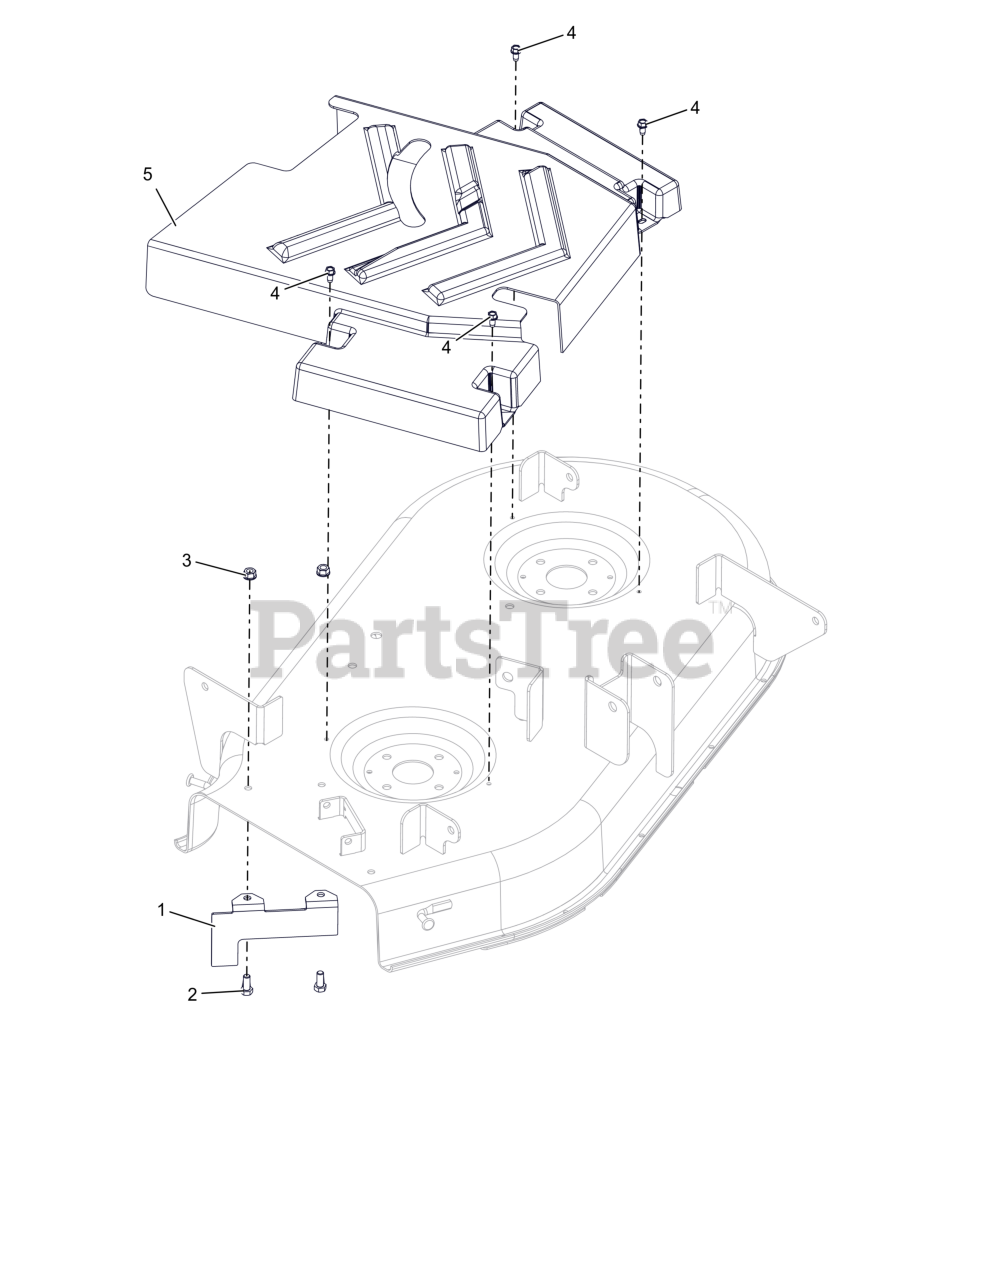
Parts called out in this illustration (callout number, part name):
1	BRKT-BAFFLE, DISCHARGE 34"
2	BLT,HEX .31-18X.75 G5 ZCC
3	NUT,LK-CTR-FLG .31-18 GF ZCC
4	SCR-TAP .25-20X.50 HWH ZCC
5	GUARD, BELT 34" CE
